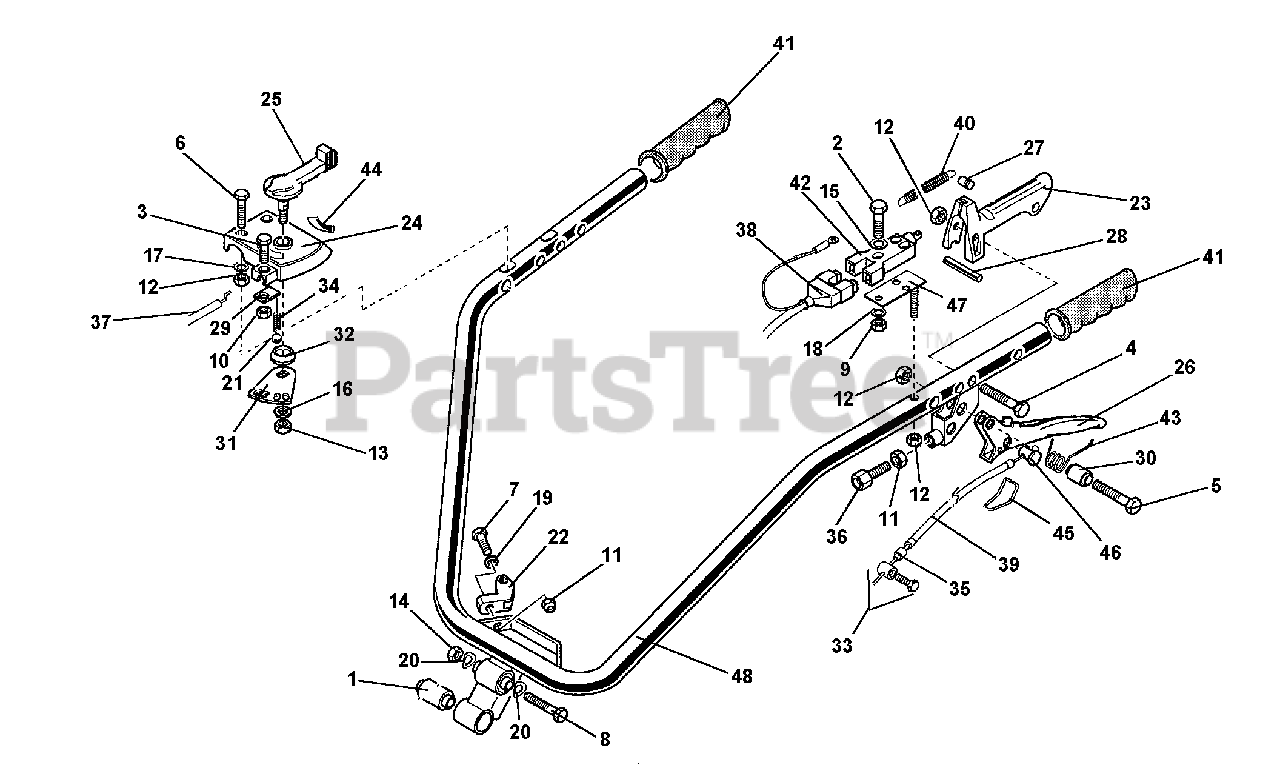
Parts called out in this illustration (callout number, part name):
1	SILENTBLOCK
2	SCREW TE M4X25
3	SCREW, M5X10
4	SCREW, TE M6X45
5	SCREW, M6X25
6	SCREW, M6X40
7	SCREW, M8X35
8	SCREW, M10X80
12	NUT, SELF LOCKING M6
15	FLAT WASHER, M4.3
16	WASHER, M8.4
17	LOCK WASHER, M6.4
18	LOCK WASHER, M4.3
19	WASHER, M8.4
20	WAVE WASHER, M10.4
22	SUPPORT, CONTROL ROD
23	MOTOR STOP LEVER
25	THROTTLE LEVER
26	CLUTCH LEVER
28	LEVER STOP FOR MOTOR STOP
30	LEVER SPACER
31	THROTTLE LEVER
33	CLAMP, CABLE
36	SCREW, ADJUSTING, M8
37	THROTTLE CABLE, B&S
38	SWITCH WIRING HARNESS
39	CLUTCH CABLE
42	STOP SWITCH
43	LEVER SPRING
44	THROTTLE DECAL
47	SWITCH PLATE
